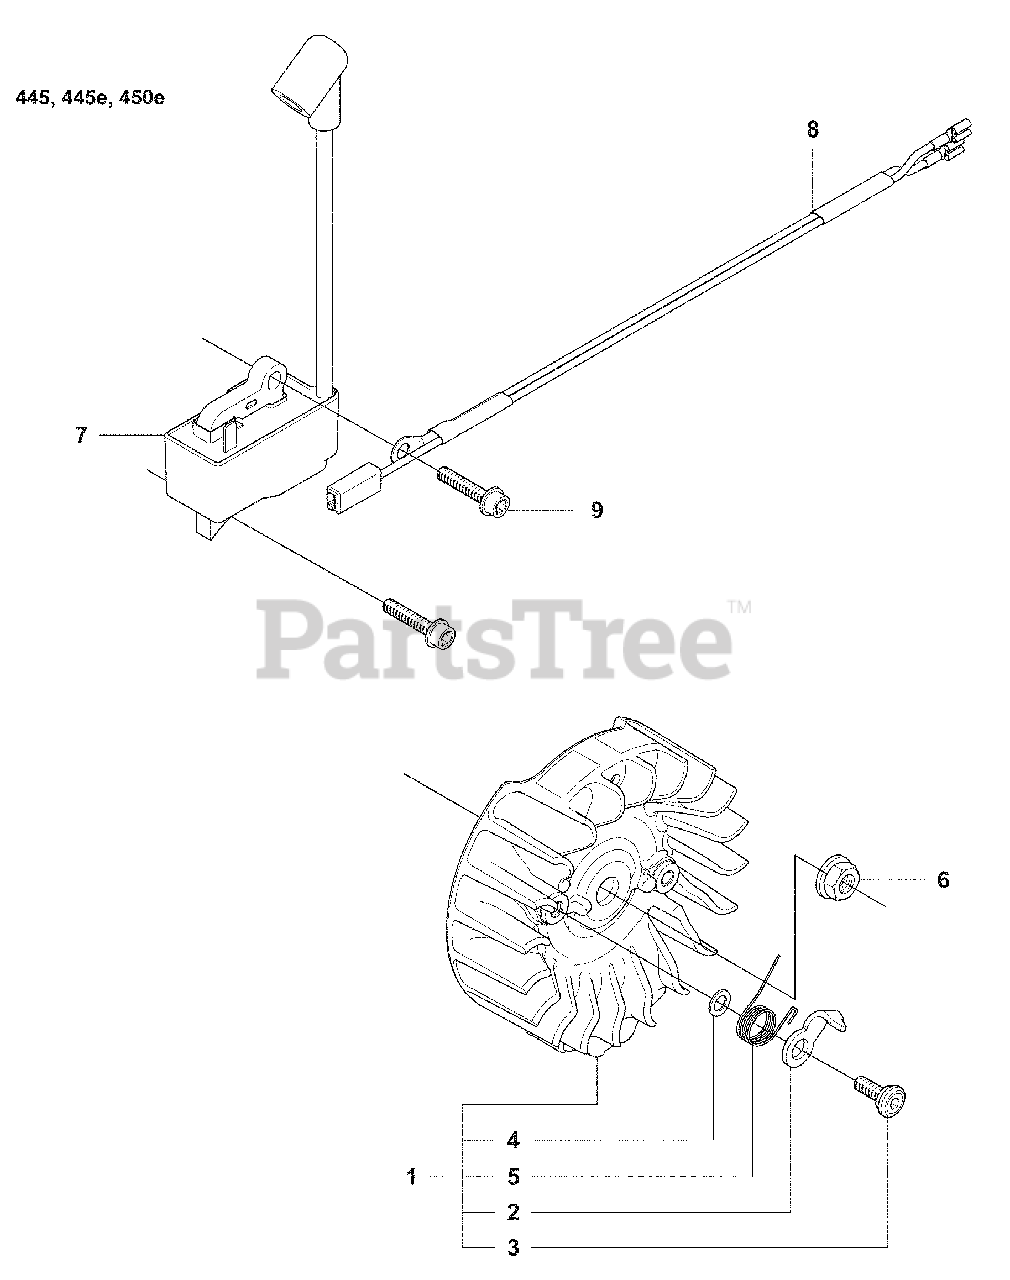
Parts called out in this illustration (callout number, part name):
1	Flywheel Assembly
2	Starter Pawl
3	Starter Catch Screw
5	Spring
6	Nut with Washer
7	Ignition Module, WALBRO MBU
8	Wiring Assembly
